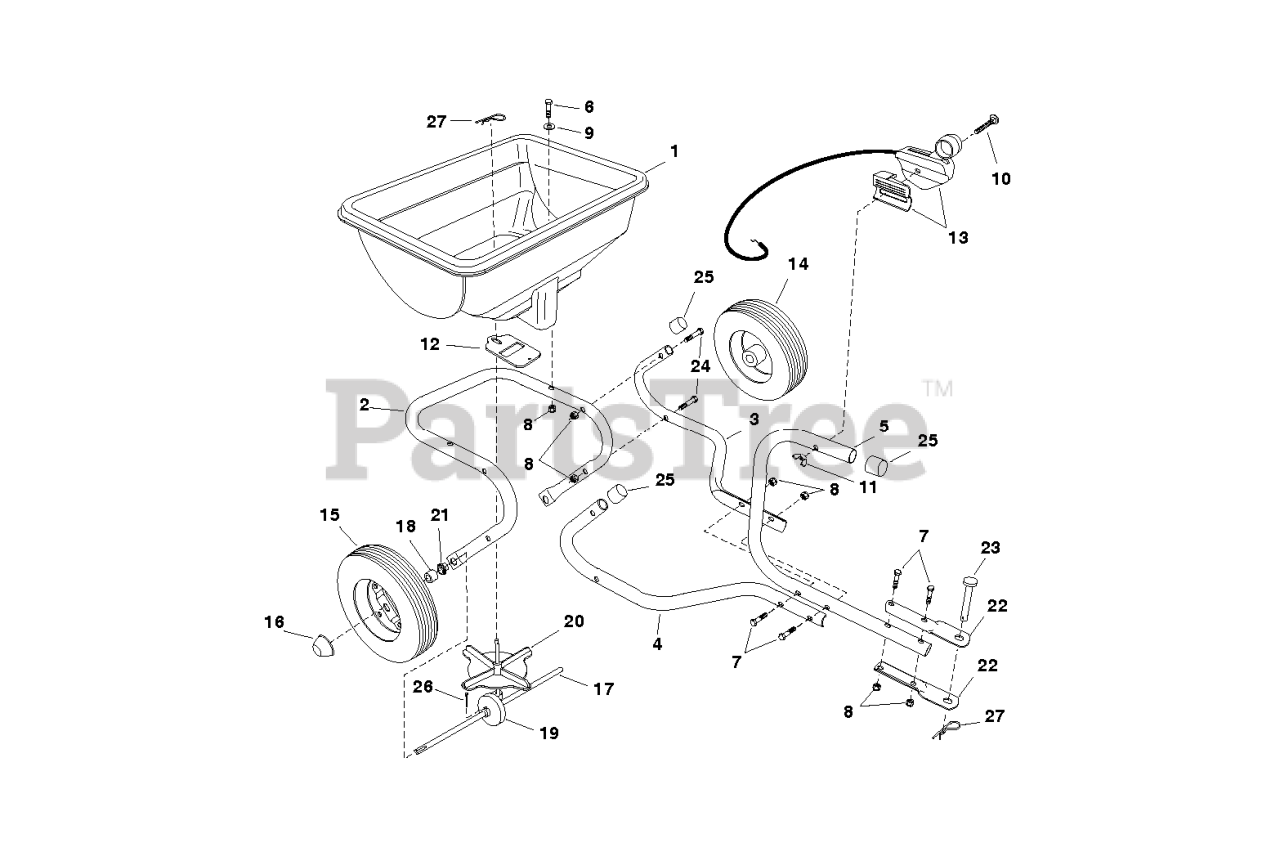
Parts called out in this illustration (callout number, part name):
13	CONTROL CABLE ASSY
17	AXLE.1/2".OD.AGRI-FAB
19	AXLE.1/2".OD.AGRI-FAB
20	AXLE.1/2".OD.AGRI-FAB
